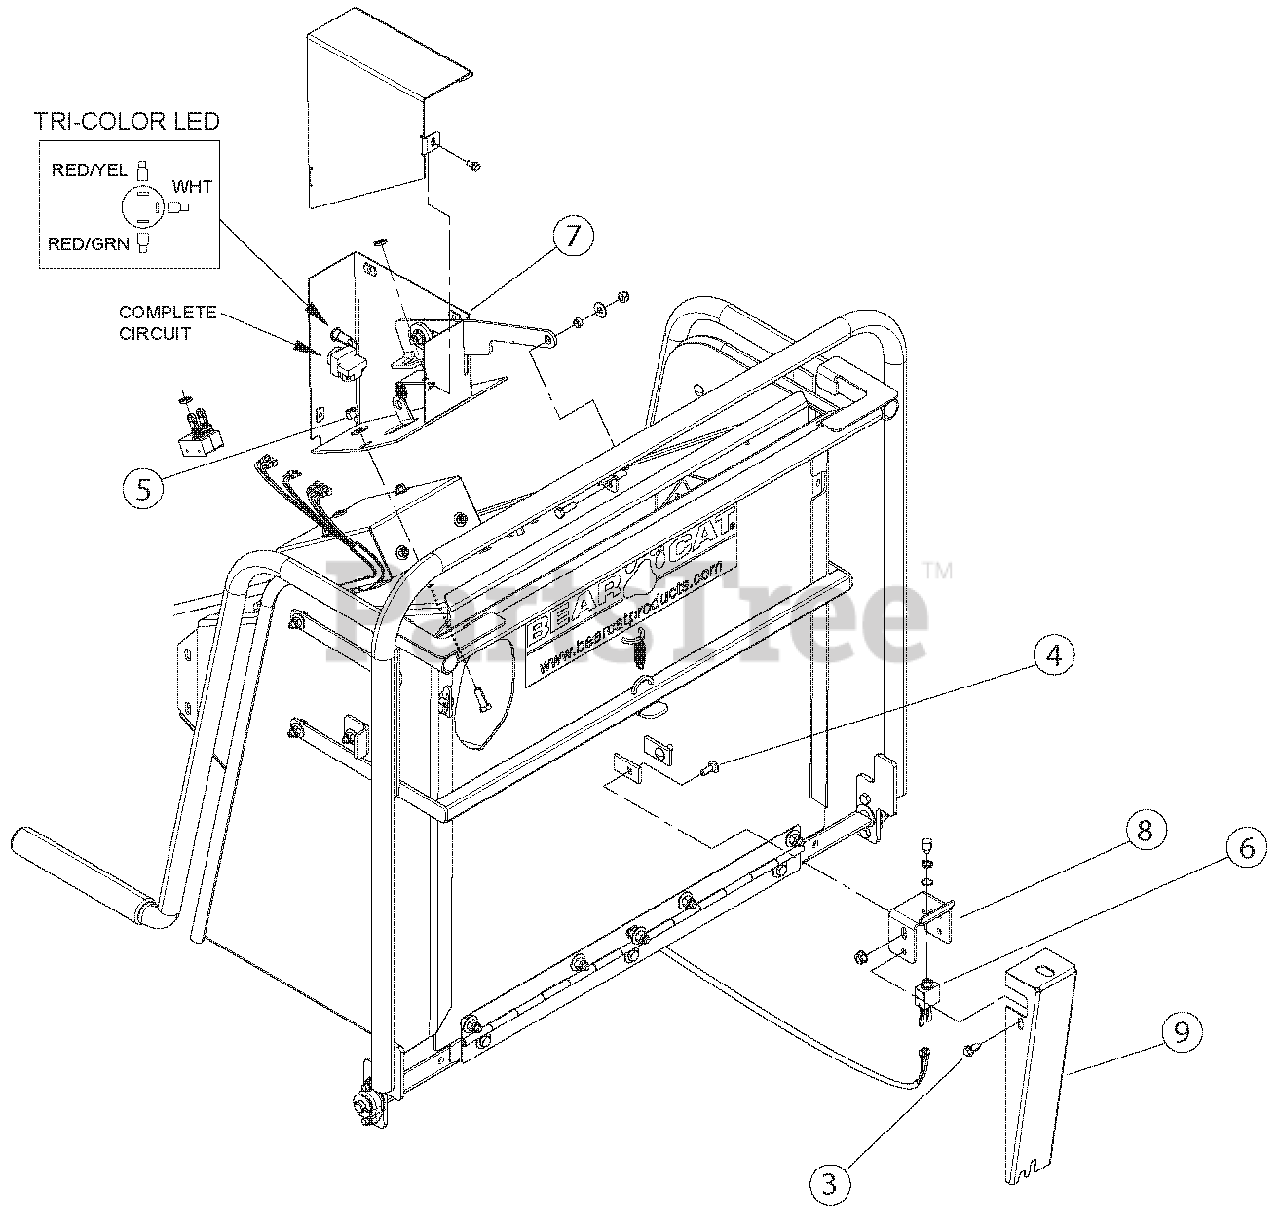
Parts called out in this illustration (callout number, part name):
1	CONNECTOR, 1/4 QD FEMALE (NOT PICTURED)
2	CONNECTOR, 1/4 QD MALE (NOT PICTURED)
3	SCW,11/32*7/8 HWH AB THREAD ZP
4	BOLT,CARR 5/16*7/8" GR5 NC ZP
5	NUT, 5/16-18 NYLOCK-FLANGE
6	SWITCH, MOMENTARY IP67 NORMALLY ON
7	ASSEMBLY, SWITCH BOX
8	BRACKET, SWITCH
9	SHIELD, SAFETY BAR SWITCH
